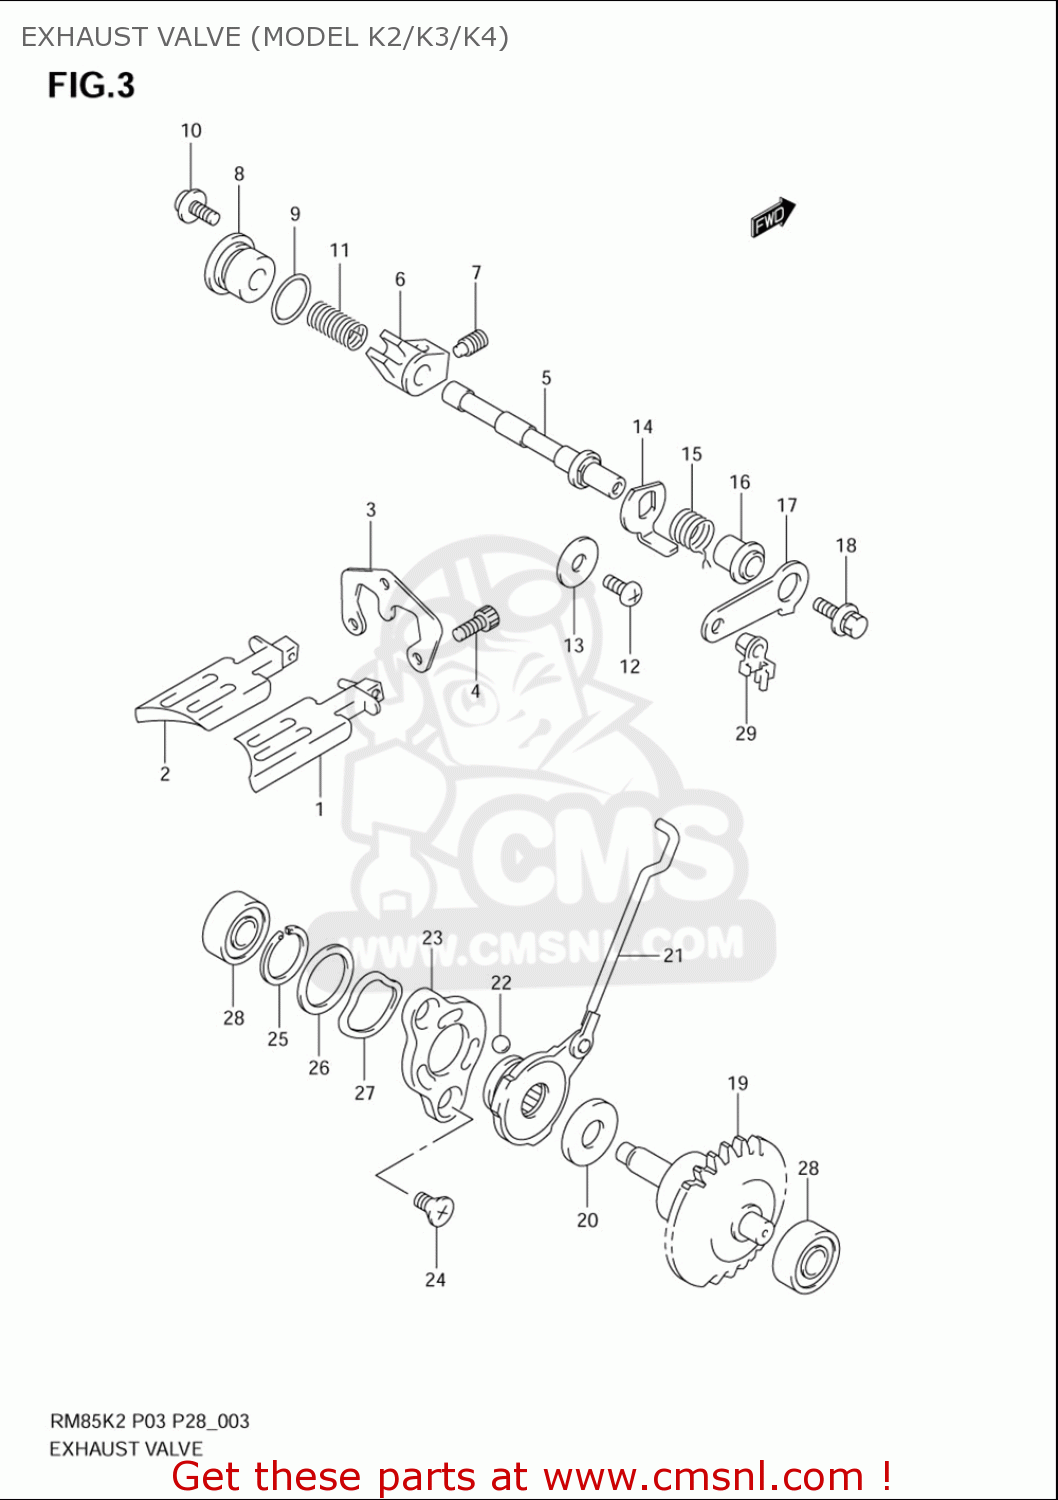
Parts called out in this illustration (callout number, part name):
1	VALVE,EXHAUST,R
2	VALVE,EXHAUST,L
3	PLATE,EXHAUST VALVE
4	BOLT
5	SHAFT,EXHAUST VALVE
6	ARM,EXHAUST VALVE SHAFT
7	SCREW(6X10)
8	CAP,EXHAUST VALVE
9	O RING(D:1.9,ID:14.5)
10	BOLT
11	SPRING
12	SCREW
13	WASHER
14	LEVER,EXHAUST VALVE NO.2
15	SPRING
16	SPACER,EXHAUST VALVE
17	LEVER,EXHAUST VALVE NO.1
18	BOLT(5X12)
19	GOVERNOR ASSY,EXHAUST VALVE
20	BEARING(10X22X2.8)
21	ACTUATOR,EXHAUST VALVE
22	BALL
23	STARTER,EXHAUST VALVE ACTUATOR
24	SCREW(5X10)
25	CIRCLIP
26	SHIM(19.1X25X0.3)
27	WASHER
28	BEARING(8X22X7)
29	BUSH,EXHAUST VALVE ROD NO.1
